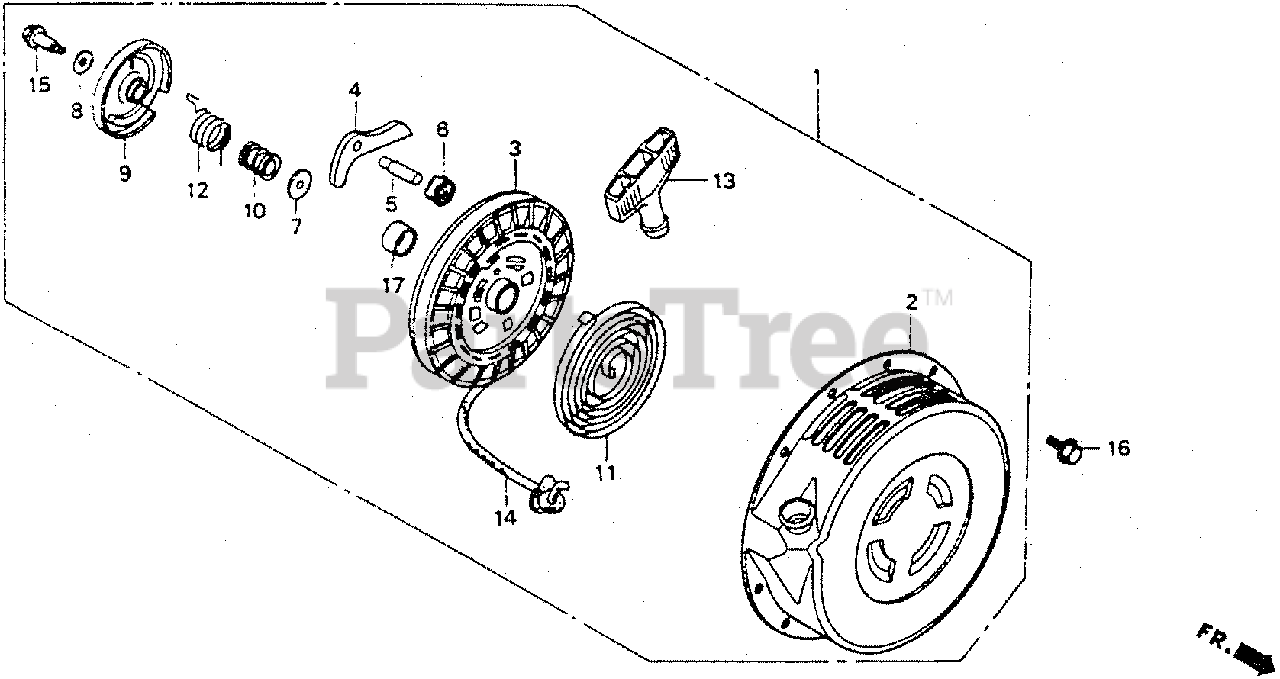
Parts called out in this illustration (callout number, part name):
1	STARTER ASSY., RECOIL
2	CASE, STARTER
3	REEL, STARTER
4	RATCHET, STARTER
5	SHAFT, RATCHET
6	PLATE, GUIDE
7	PLATE A, FRICTION
8	PLATE B, FRICTION
9	COVER, REEL STARTER
10	SPRING, FRICTION
11	SPRING, RETURN
12	SPRING, TORSION
13	GRIP, STARTER
14	ROPE, STARTER (#6X64")
15	BOLT, REEL COVER
16	BOLT, FLANGE (6X8)
17	COLLAR
